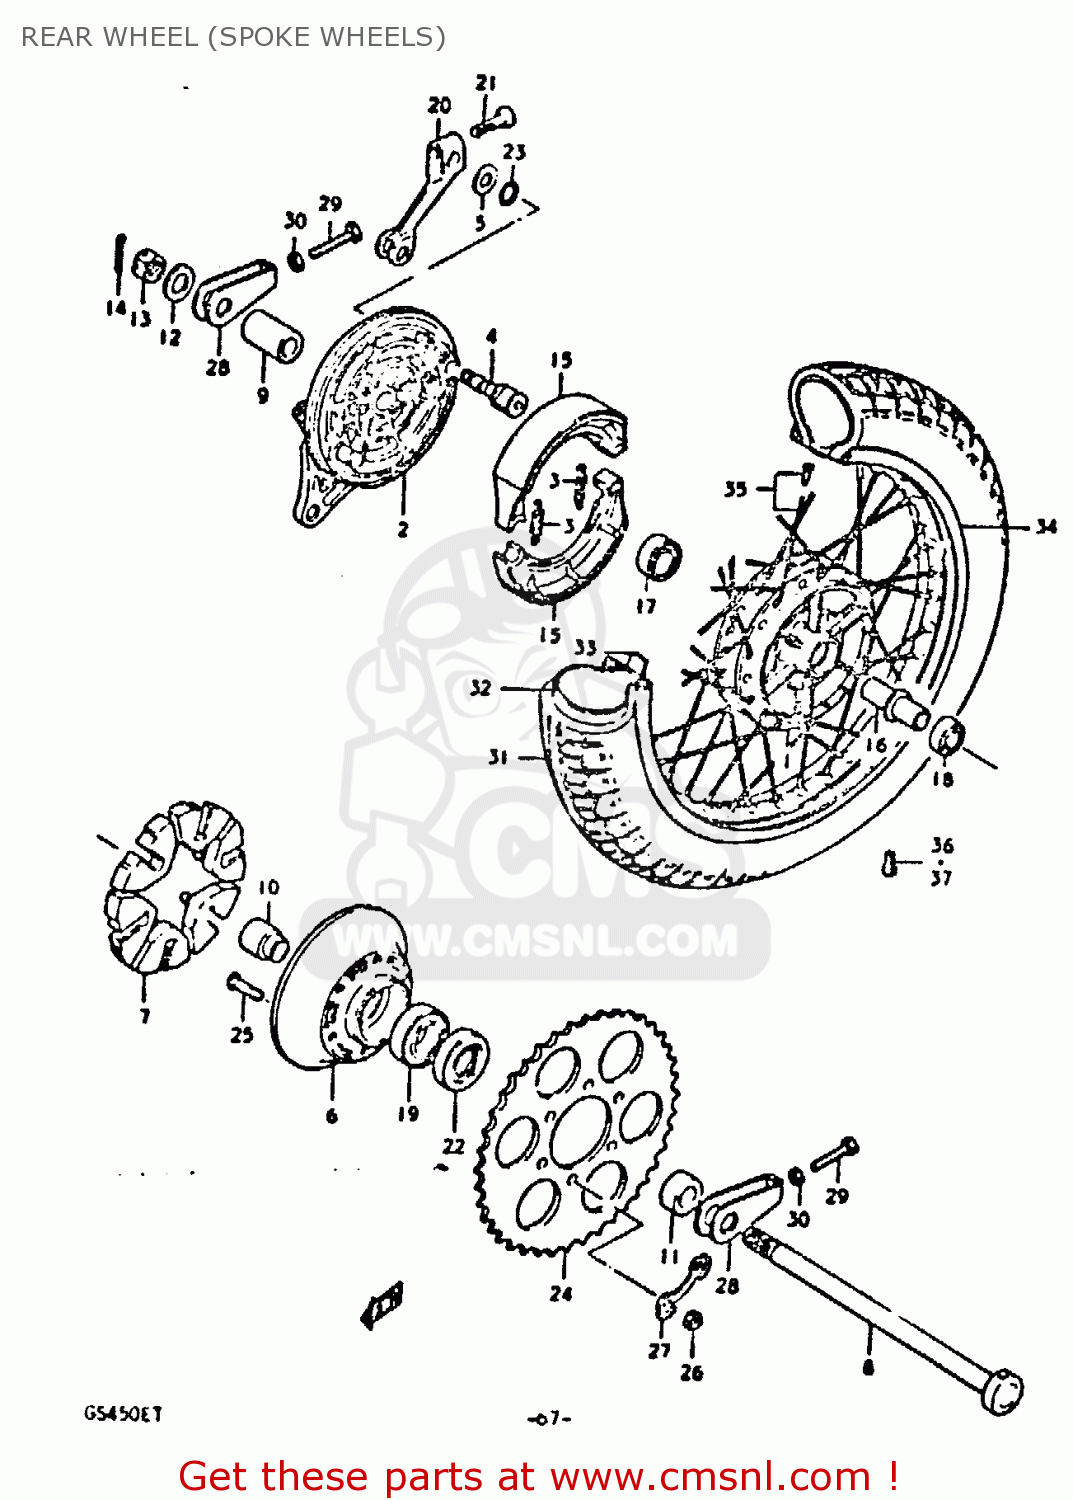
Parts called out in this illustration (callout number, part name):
1	DRUM,REAR HUB
2	PANEL,REAR HUB
3	SPRING,BRAKE SHOE
4	CAM,FRONT BRAKE
5	WASHER (15X24X1.6)
6	DRUM,REAR SPROCKET MOUNT
7	CUSHION,REAR DRUM
8	AXLE,REAR
9	SPACER(17.5X28X44.8)
10	SPACER,REAR HUB BEARING
11	SPACER(17X30.5X22.3)
12	WASHER (17X30X3.2)
13	NUT
14	PIN,COTTER
15	SHOE SET,BRAKE (MCA)
16	SPACER
17	BEARING
18	BEARING
19	BEARING
20	LEVER,REAR BRAKE CAM
21	BOLT
22	OIL SEAL
23	O-RING,BOSS
24	SPROCKET,RR
25	BOLT
26	NUT
27	WASHER
28	ADJUSTER,CHAIN
29	BOLT
30	NUT
31	TIRE
32	TUBE ASSEMBLY,WHEEL,INNER
33	PROTECTOR,INNER TUBE
34	RIM,RR WHEEL
35	SPOKE SET,FRONT
36	BALANCER,WHEEL (B)
37	BALANCER,WHEEL (30G)
